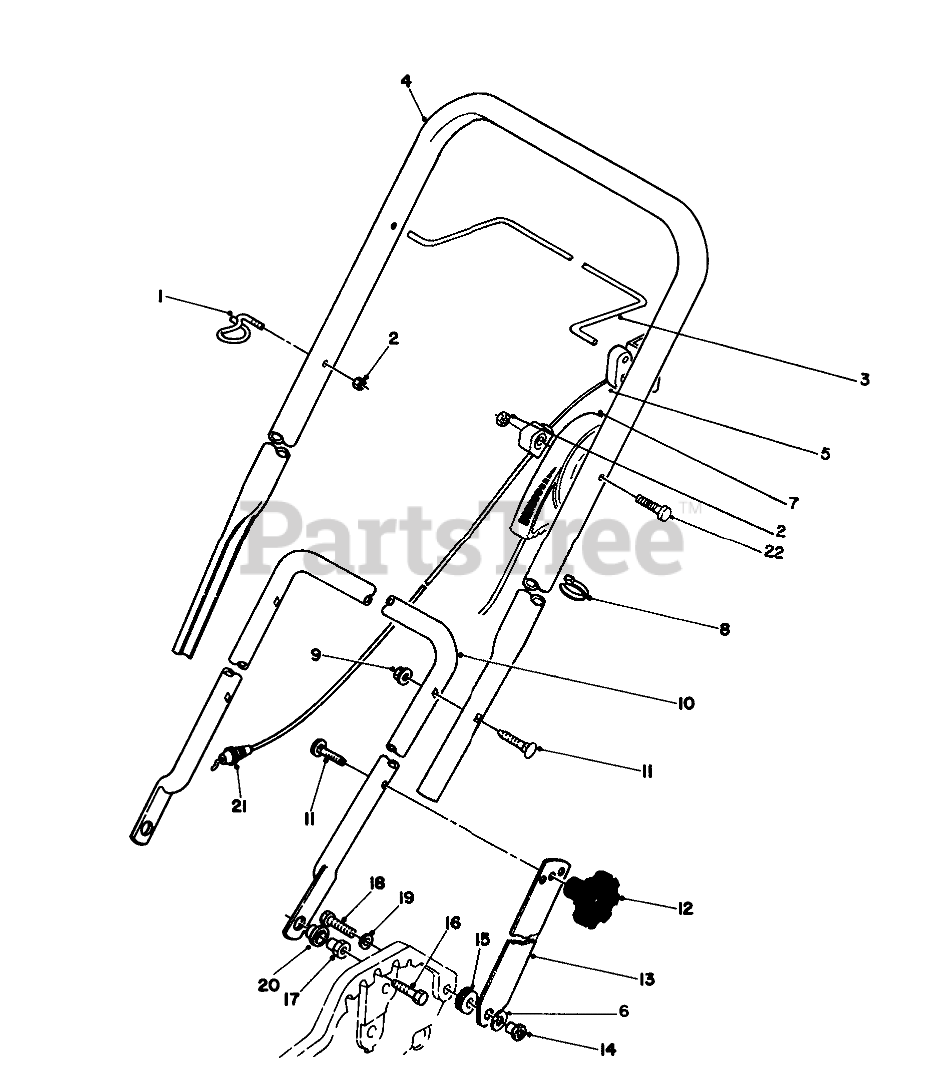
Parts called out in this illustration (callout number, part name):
1	GUIDE-ROPE
2	NUT-LOCK, NI
3	Bar-Control
4	UPPER HANDLE
5	STOP-PIVOT
6	WASHER
7	THROTTLE CABLE
8	TIE-CABLE
9	NUT-LOCK NI
10	LOWER HANDLE(CROM)
11	SCREW-HANDLE
13	HANDLE LATCH
14	POST-MOUNTING, LINKAGE
15	GROMMET
16	SCREW-HH
17	HANDLE PIVOT NUT
18	SCREW-HH
19	WASHER-LOCK
20	FLANGE BUSHING
21	BRAKE CABLE
22	SCREW-HH
